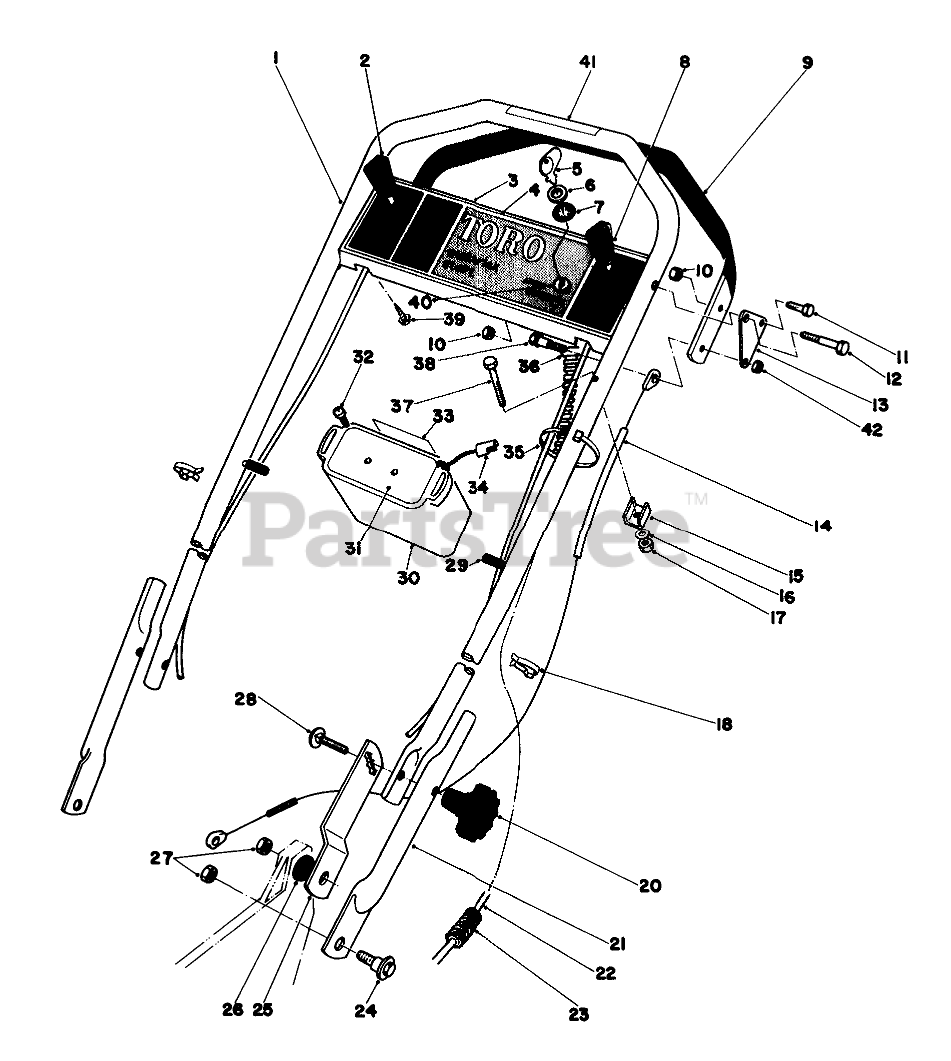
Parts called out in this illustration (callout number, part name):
1	Upper Handle
2	Ground Speed Control
3	Control Panel
4	Decal-Key Lectric
5	Key
6	NUT-HH
7	WASHER-TOOTH, INTERNAL
8	Throttle Control
9	DEMAND HANDLE ASM
10	NUT-LOCK, CONE
11	SCREW-HH
12	BOLT-SHOULDER
13	Bracket Demand
14	DEMAND HAND CABLE
15	CLAMP-CABLE
16	WASHER-FLAT
17	NUT-LOCK, NI
18	BOWDEN CLIP
21	LOWER HANDLE
22	WIRE HARNESS
23	Cover-Wiring Harness
24	SCREW-SHOULDER
25	Handle Latch L.H.
26	SPACER
27	Nut
28	SCREW-CARR
29	CAP-VINYL
30	Battery Case
31	BATTERY COVER
33	Decal
34	Plug & Wire
35	TIE-CABLE
36	RING FITTING
37	SCREW-HH
38	Shoulder Bolt
39	SCREW-HWHTF
40	Starter Switch (Incl. Ref. #5-7)
41	Decal-Danger
42	NUT-HEX, SIDE DEFORM
